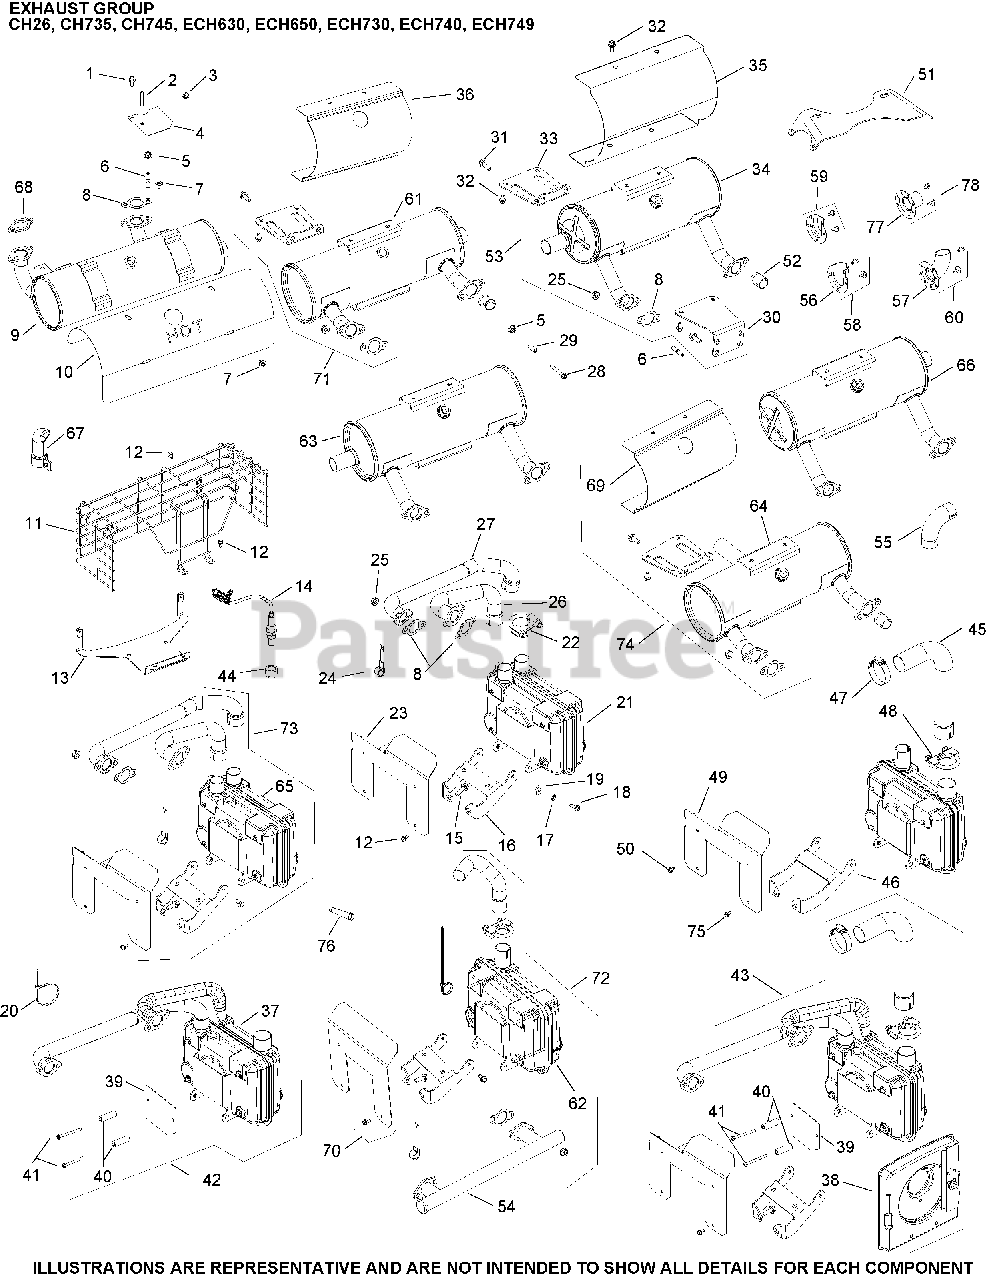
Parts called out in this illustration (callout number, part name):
5	NUT, HEX FLANGE LOCK (M8)
8	GASKET, EXHAUST
14	SENSOR, OXYGEN (M18 x 1.5 THREADS)
28	SCREW, FLG M6X1.0X40
29	SPACER .281 X .500 X .875
30	BRACKET, MUFFLER
31	SCREW, FLG M8X1.25X20
32	SCREW, FLG M6X1.0X12
36	SHIELD, HEAT USE 24 314 56-S
52	LINER, EXHAUST PORT
66	KIT, MUFFLER USE 24 068 145-S
